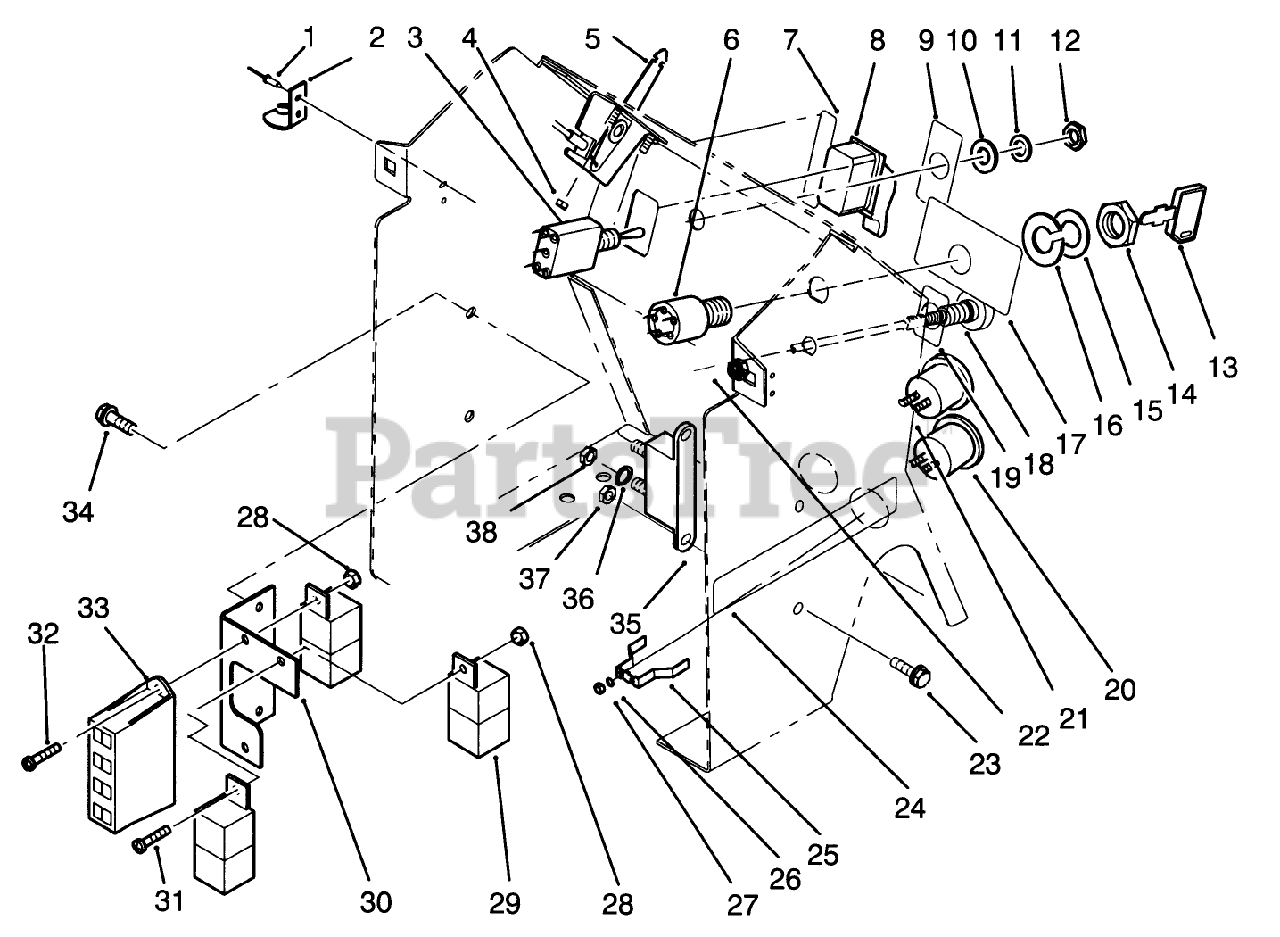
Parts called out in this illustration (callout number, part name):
2	KEEPER-LATCH
3	SWITCH-LIGHTS
5	CONTROL-THROTTLE
6	KEY SWITCH ASM
8	PTO-SWITCH W/COVER
9	DECAL-LIGHTS
10	TAB-WASHER
11	WASHER
12	*DISC**
13	KEY-IGNITION
18	CONTROL-CHOKE
21	VOLTMETER
22	NUT-HJ
23	SCREW-HHF
25	CLAMP-HOUR METER
26	WASHER-LOCK
29	RELAY
31	SCREW-PPH
32	SCREW
36	WASHER-LOCK
37	NUT-HEX
38	NUT-JAM
